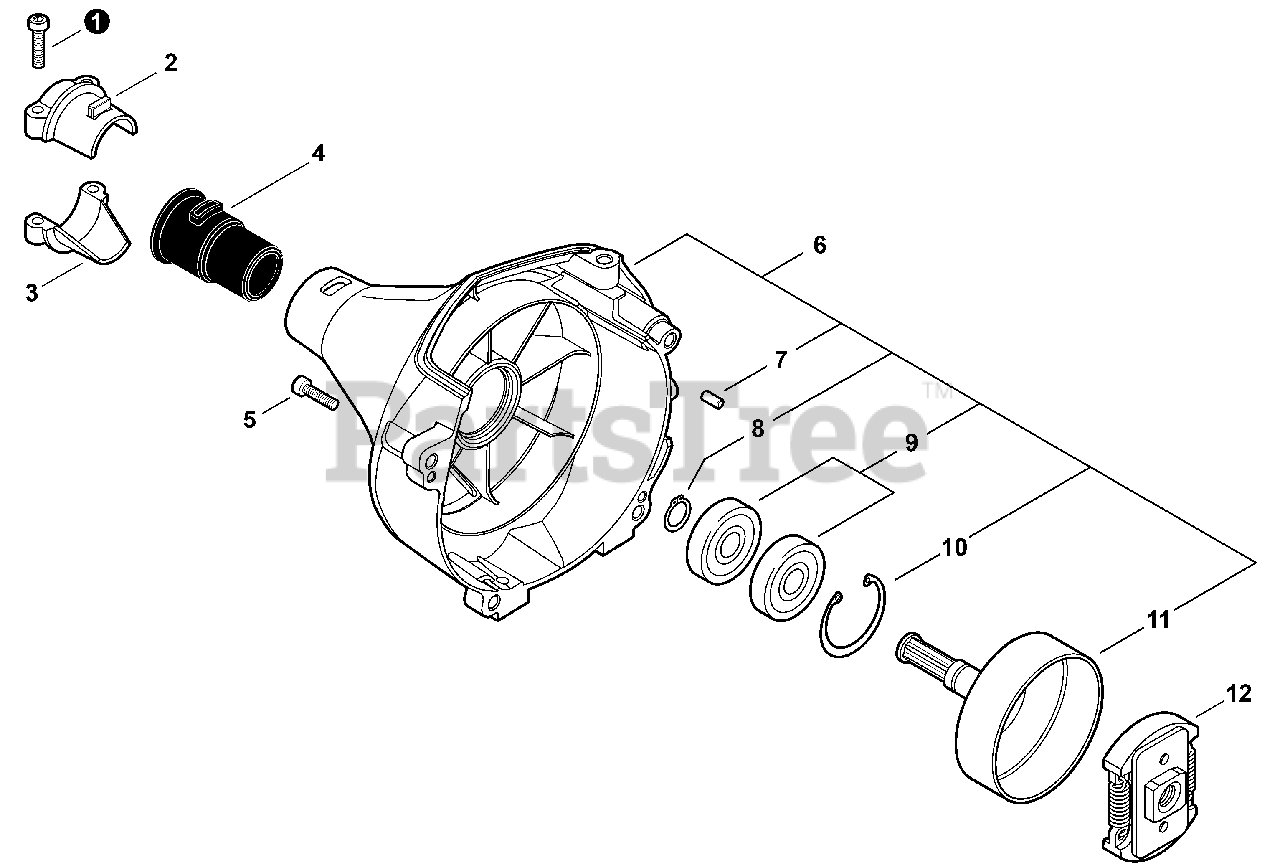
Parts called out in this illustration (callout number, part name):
1	BOLT, TORX 5×20
2	HOLDER, MAIN PIPE - UPPER
3	HOLDER, MAIN PIPE - LOWER
4	CUSHION Ø25
5	BOLT, TORX 4×16
6	COVER ASSY, FAN
7	PIN, LOCATING 4
8	RING, RETAINING - 12
9	BEARING, BALL 6001
10	RING, SNAP 28
11	DRUM, CLUTCH
12	CLUTCH ASSY
